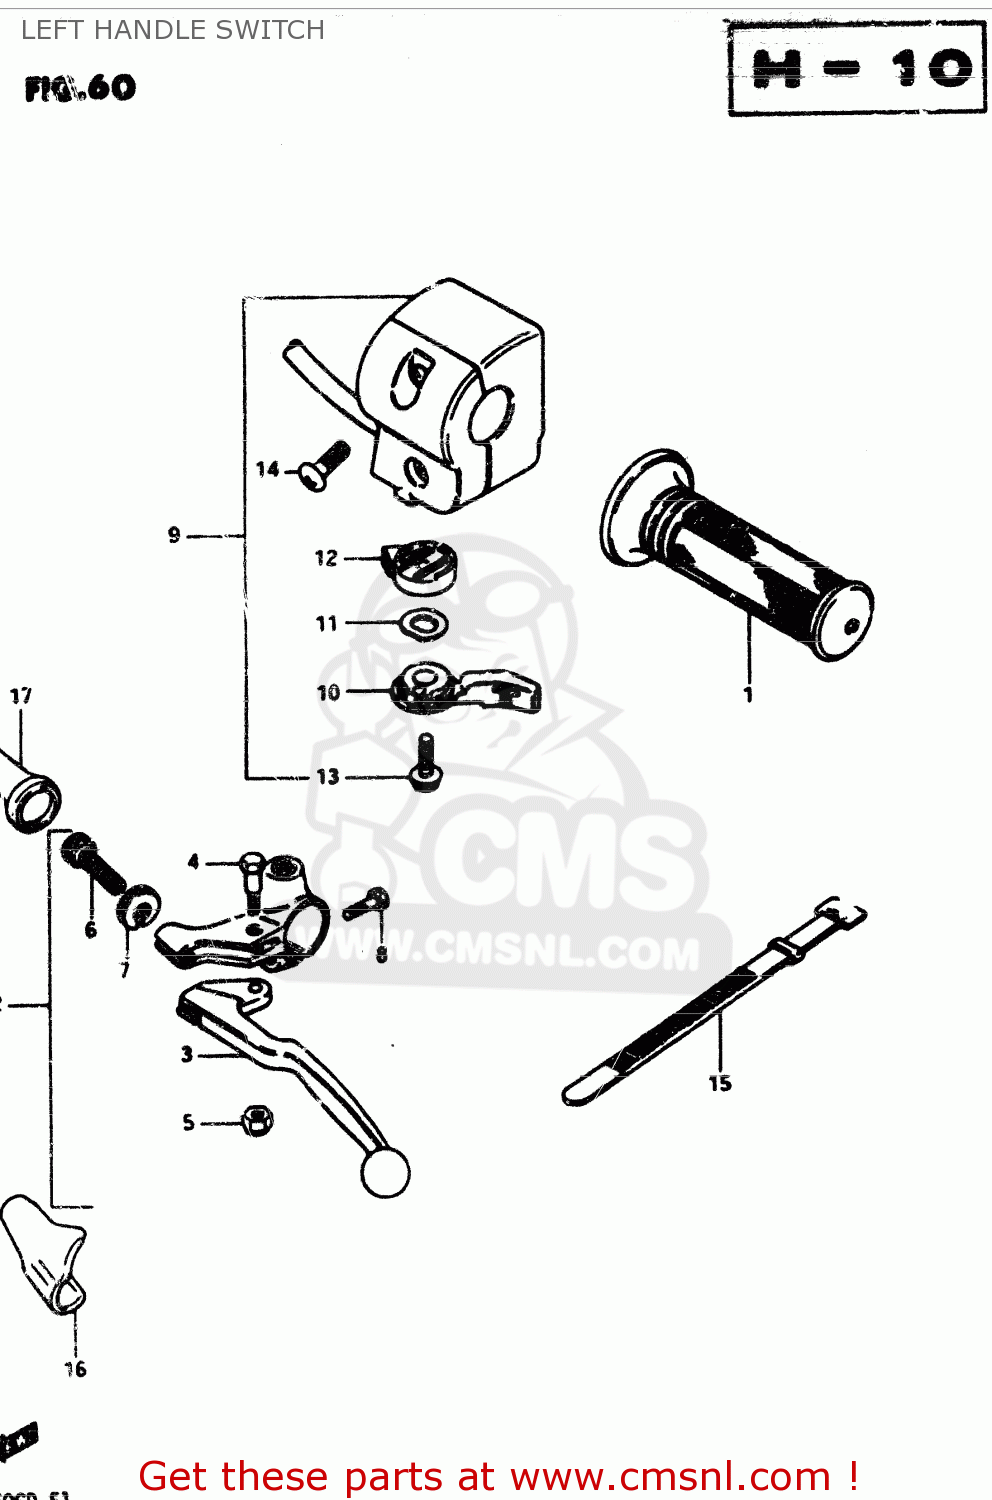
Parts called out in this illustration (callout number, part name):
1	GRIP,LEFT
2	LEVER ASSEMBLY
3	LEVER,CLUTCH
4	BOLT,LEVER
5	NUT 6MM
6	ADJUSTER,CABLE
7	NUT,CABLE ADJUSTER
8	BOLT
9	SWITCH ASSY, HANDLE LH (FLAT)
10	LEVER,STARTER
11	WASHER,ADJUSTER
12	BODY,CHOCK
13	SCREW,CHOKE LE
14	SCREW
15	CLAMP(L:120)
16	COVER,CLUTCH LEVER
17	BOOT,CLUTCH CABLE
